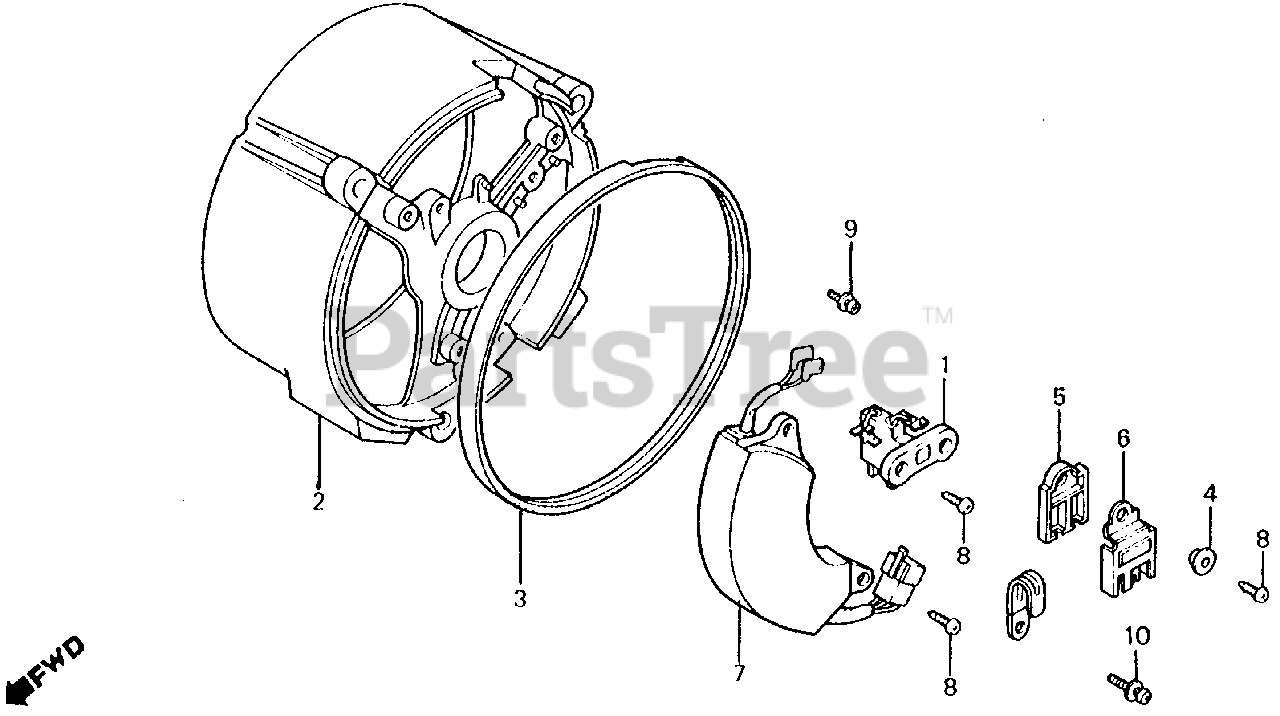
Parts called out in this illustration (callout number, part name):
1	BRUSH ASSY.
2	HOUSING, RR. *NH105* (MAT BLACK)
3	SEAL, GENERATOR (NOT AVAILABLE)
4	BUSH, INSULATING
5	INSULATOR, DIODE
6	DIODE, D.C.
7	REGULATOR ASSY., AUTOMATIC VOLTAGE (NOT AVAILABLE)
8	SCREW, TAPPING (5X14)
9	SCREW, PAN (5X12)
9	SCREW, PAN (5X8)
10	SCREW-WASHER (5X55) (NOT AVAILABLE)
